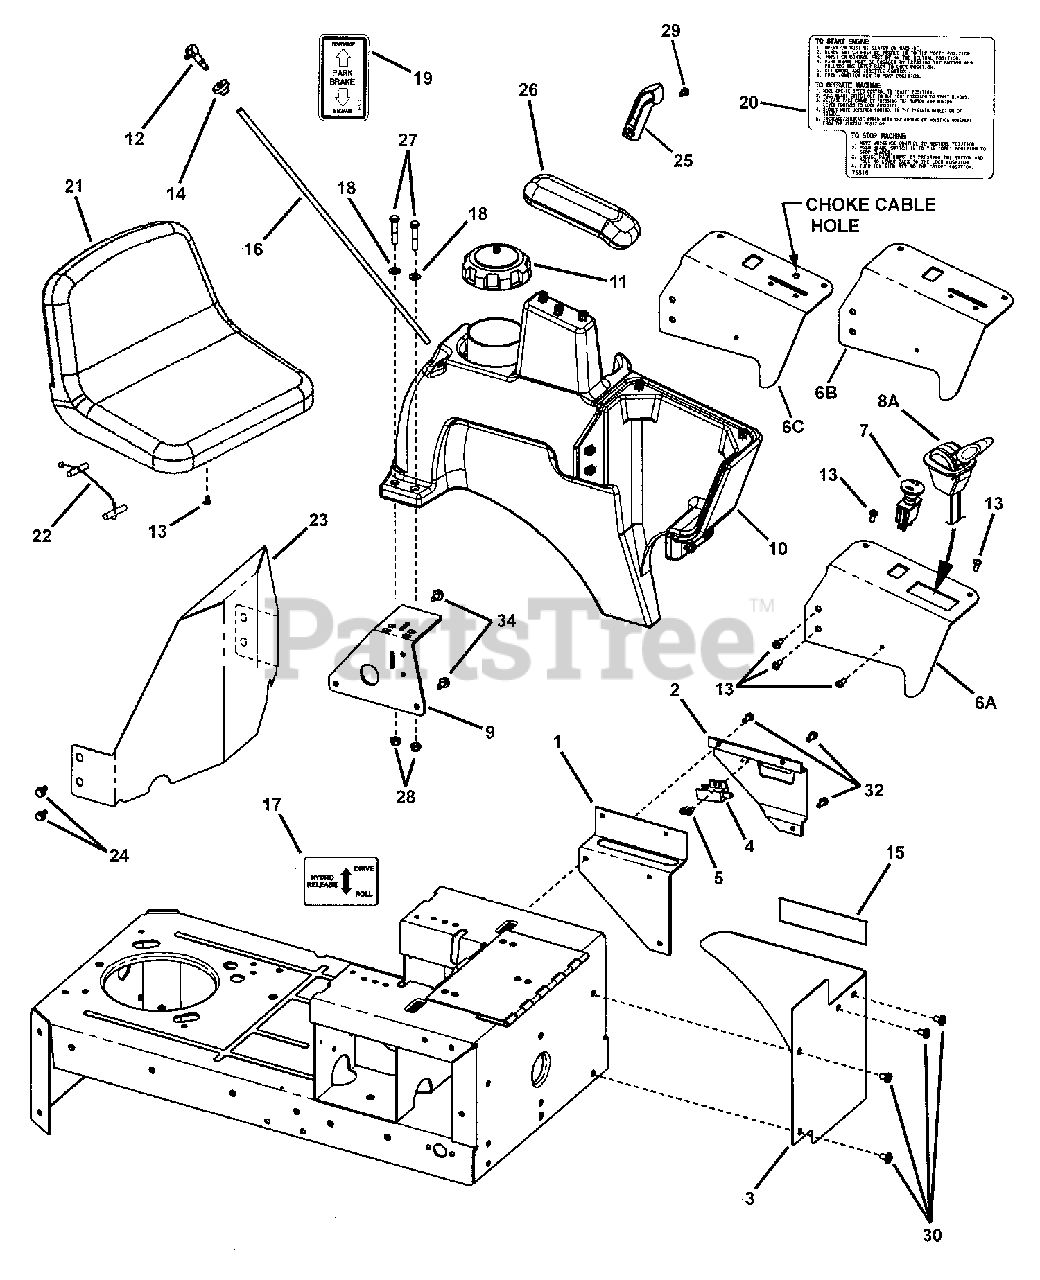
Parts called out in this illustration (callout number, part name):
1	BRACKET, L.H. Tank Support
2	BRACKET, Brake/Clutch Detent
3	FENDER, L.H. Lower
4	SWITCH, Park Brake (NC/NO)
5	SCREW, #10-24 x 1/2" Hex Washer Self-Tap (Torx)
6A	BRACKET, L.H. Console
6B	BRACKET, L.H. Console
6C	BRACKET, L.H. Console
7	SWITCH, PTO E.C. (Delta Part No. 6201-219)
8A	CONTROL, Throttle/Choke, Dual Lever
9	WELDMENT, Fuel Tank Support
10	ASSEMBLY, Fuel Tank/Left Hand Fender
11	GAS CAP w/Screw Vent
12	FITTING, Dapco
13	SCREW, 1/4-20 x 5/8" Pan Head Self-Tap
14	GROMMET
15	DECAL, SNAPPER
16	DIP TUBE
17	DECAL, Hydro Release
18	WASHER, .34 x .69 x .08 Flat
19	DECAL, Park Brake
20	DECAL, Operating Instructions
21	SEAT, Milsco High Back
22	TETHER, Seat
23	HEAT SHIELD, Engine
24	SCREW, 5/16-18 x 1/2" Hex Washer Self-Tap
25	LEVER, Throttle Control
26	ARM REST, HOZ
27	SCREW, 5/16-18 x 1-3/4" Hex Head Cap, GR 5
28	NUT, 5/16-18 Hex Nyloc
29	RIVET, Plastic Snap
30	SCREW, 5/16-18 x 1/2" Pan Head Self-Tap
32	SCREW, 1/4-20 x 5/8" Hex Washer Self-Tap
34	SCREW, 5/16-18 x 5/8" Hex Washer Self-Tap
